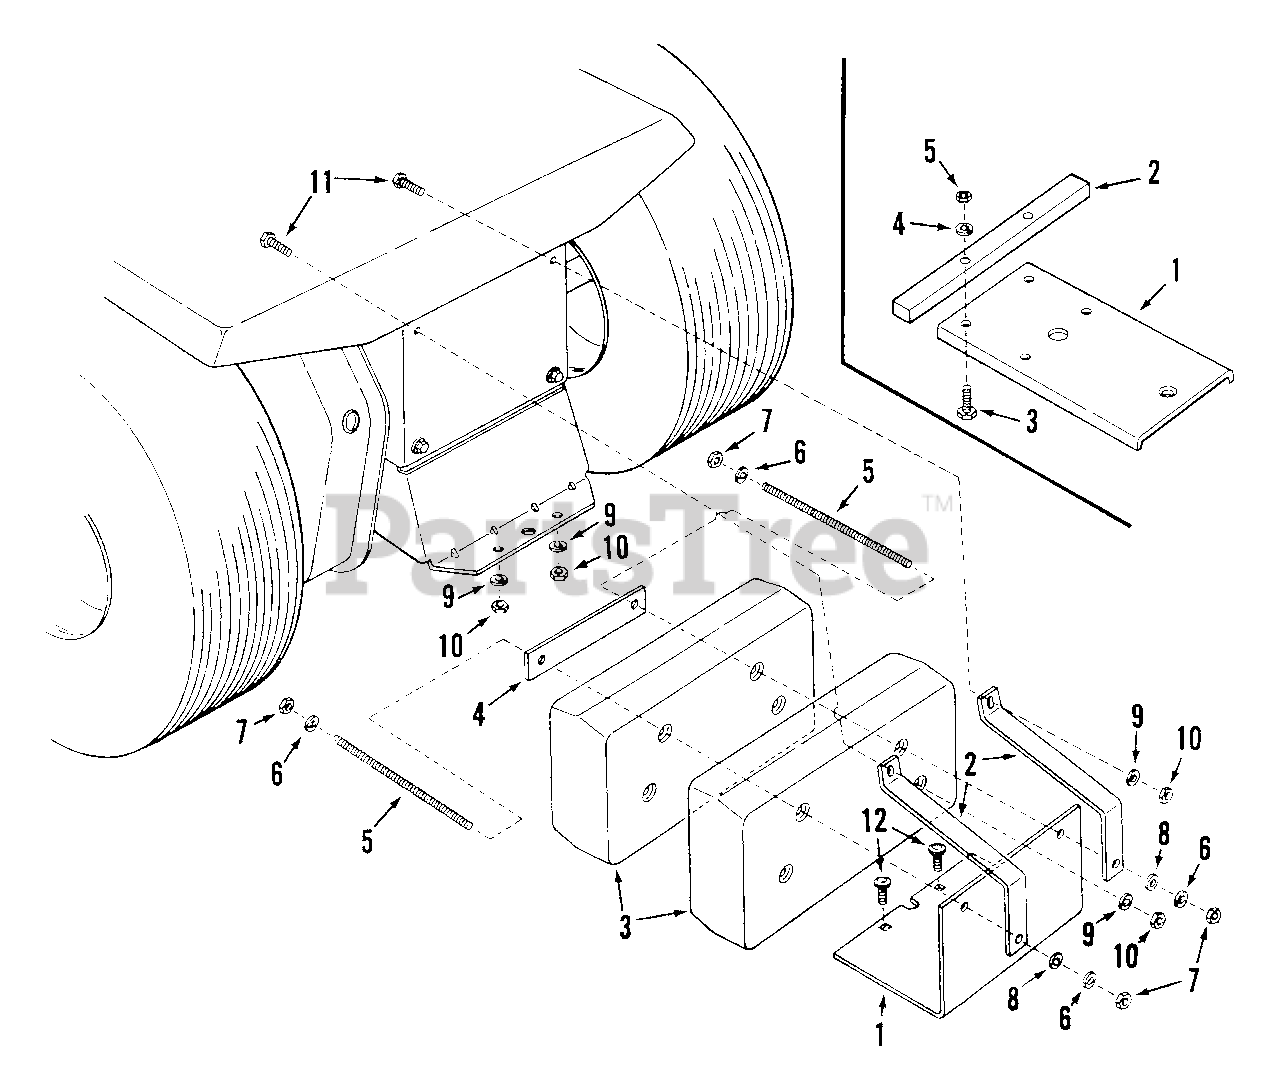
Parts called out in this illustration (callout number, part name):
2	SUPPORT
3	WEIGHT (38 lb.)
4	PLATE, Retainer
5	ROD, 3/8-16 x 9" Threaded
6	WASHER, 3/8 Split Lock
7	NUT, 3/8-16 Hex
8	WASHER, 3/8 Flat SAE
9	WASHER, 5/16 Split Lock
10	NUT, 5/16-18 Hex
11	SCREW, 5/16-18 x 1" HHC Gr. 2
12	BOLT, 5/16-18 x 1" Sq. Neck Carriage
